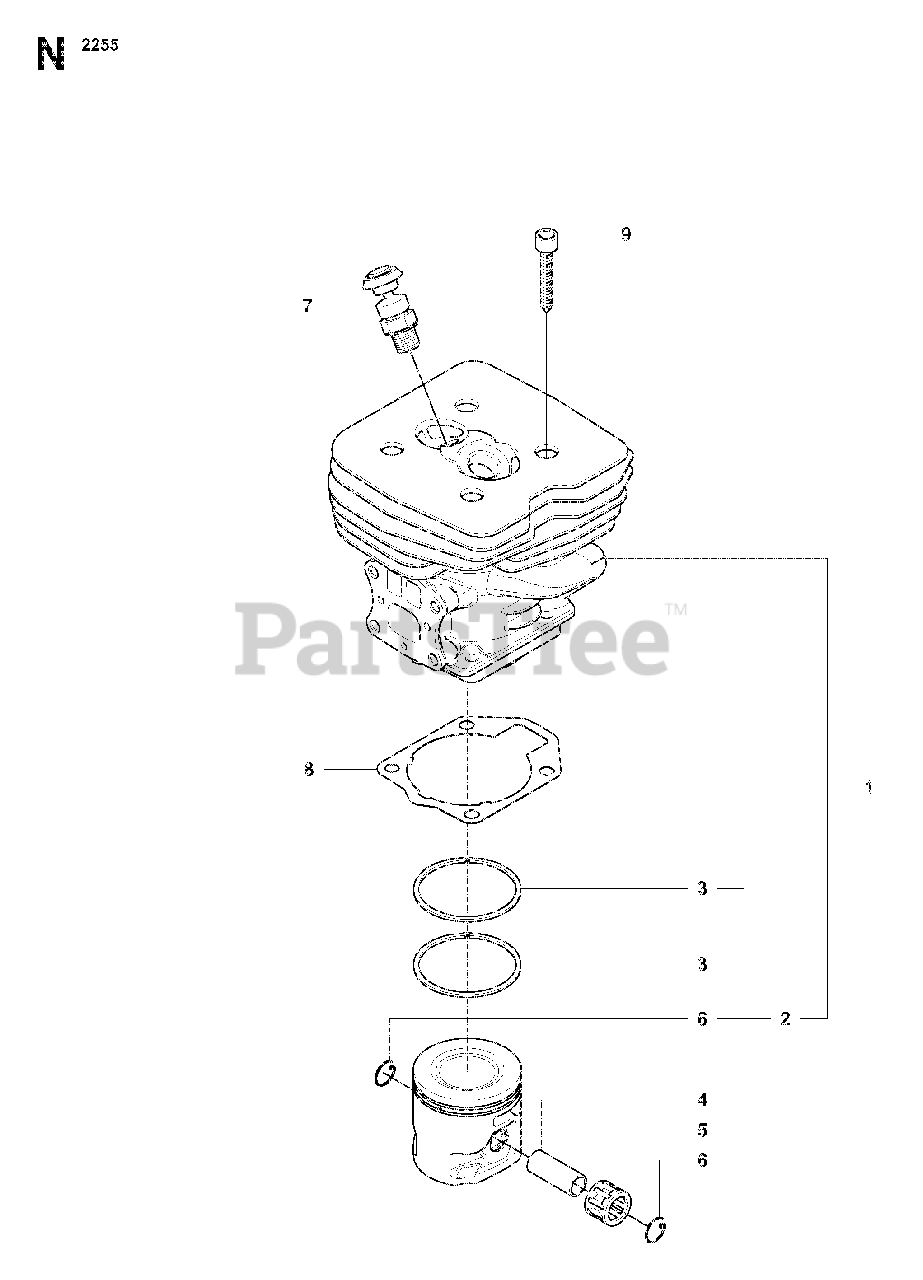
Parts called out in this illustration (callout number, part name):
1	CYLINDER ASSY
2	%PISTON ASSY
3	PISTON RING
4	PISTON PIN
5	RP SUPPORT BUSHING
6	CIRCLIP
7	DECOMPRESSION VALVE
9	SCREW MC6S 5X25
